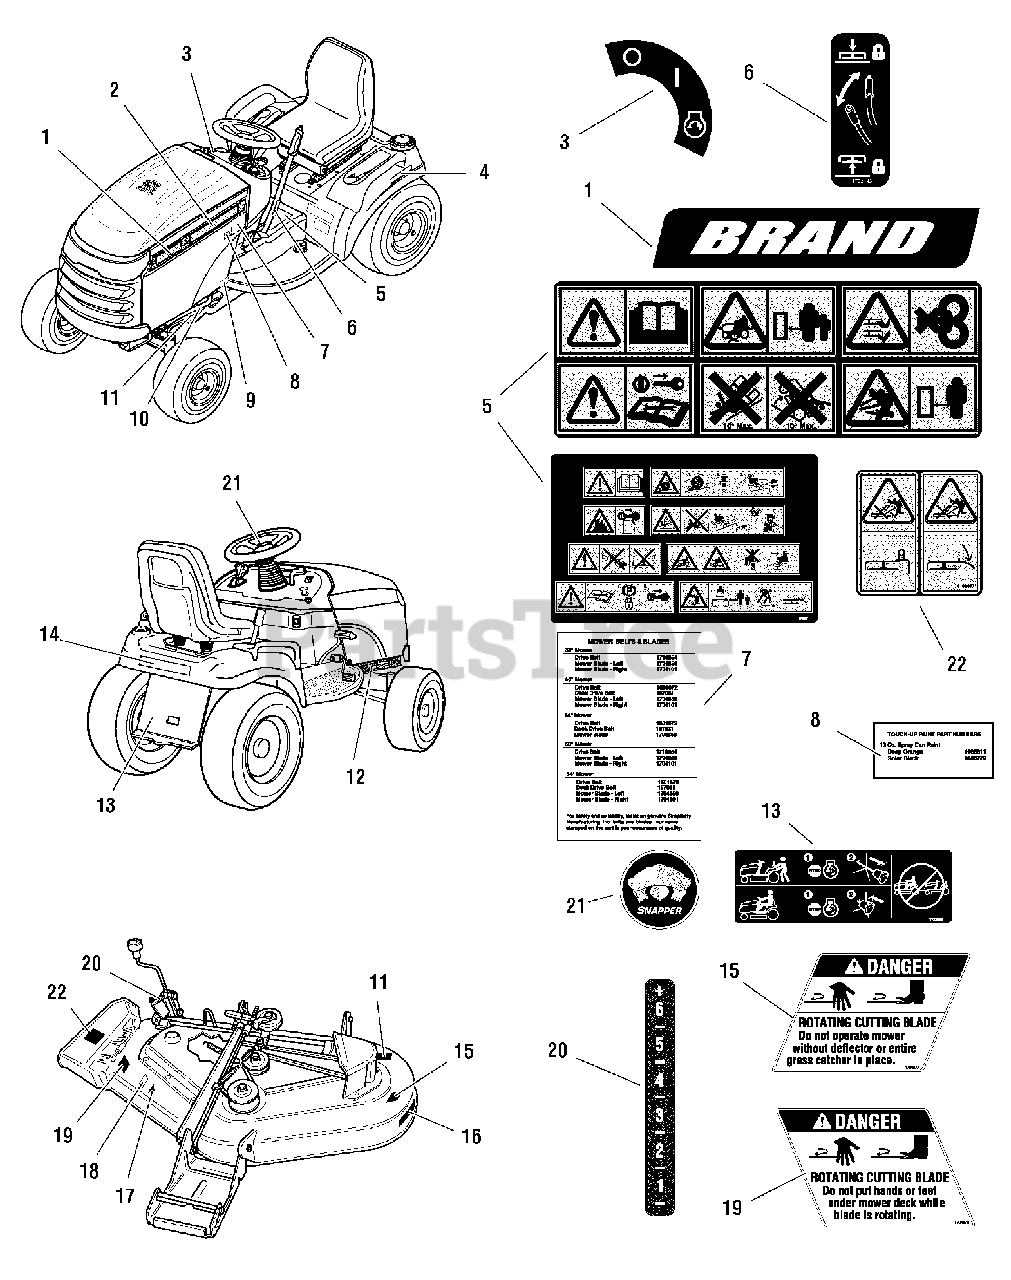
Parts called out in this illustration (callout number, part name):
1	DECAL, YT2044
1	DECAL, YT2250
1	DECAL, YT400 23HP
1	DECAL, YT2452 24HP
2	DECAL, Hood Stripe, Snapper, LH
2	DECAL, Hood Stripe, Snapper, RH
2	DECAL, Snapper, LH & RH
3	DECAL, Ignition Switch Symbols, White/Black
4	DECAL, Automatic Control Traction
5	DECAL, Tunnel Cover, Safety
5	DECAL, Tunnel Cover, Safety, 8, No Text
5	DECAL, Tunnel Cover, Safety, 6, No Text
5	DECAL, Tunnel Cover, Safety, 9, No Text, 6-1/2 x 10-1/4
6	DECAL, Lift Lever Symbols
7	DECAL, Drive Belts, Mower Blades
8	DECAL, Touch-Up Paint, Red
9	DECAL, Protective Sticker
10	LABEL, Decibel, Power Mass
11	DECAL, I.D. Plate
12	DECAL, Patent
13	DECAL, Transmission Release Valve
14	DECAL, Snapper
14	DECAL, Snapper w/stripe
14	DECAL, Snapper, Rear
15	DECAL, Danger Do Not Put Hands/Feet in Mower
16	DECAL, Free Floating Mower, Silver
17	DECAL, OPEI Certified
18	DECAL, 44", Silver on Black with Stripe
18	DECAL, 50"
18	DECAL, 52"
19	DECAL, Danger Do Not Operate Without Deflector
20	DECAL, Height of Cut
21	DECAL, Steering Wheel Icon
22	DECAL, Danger, Discharge, ANSI
